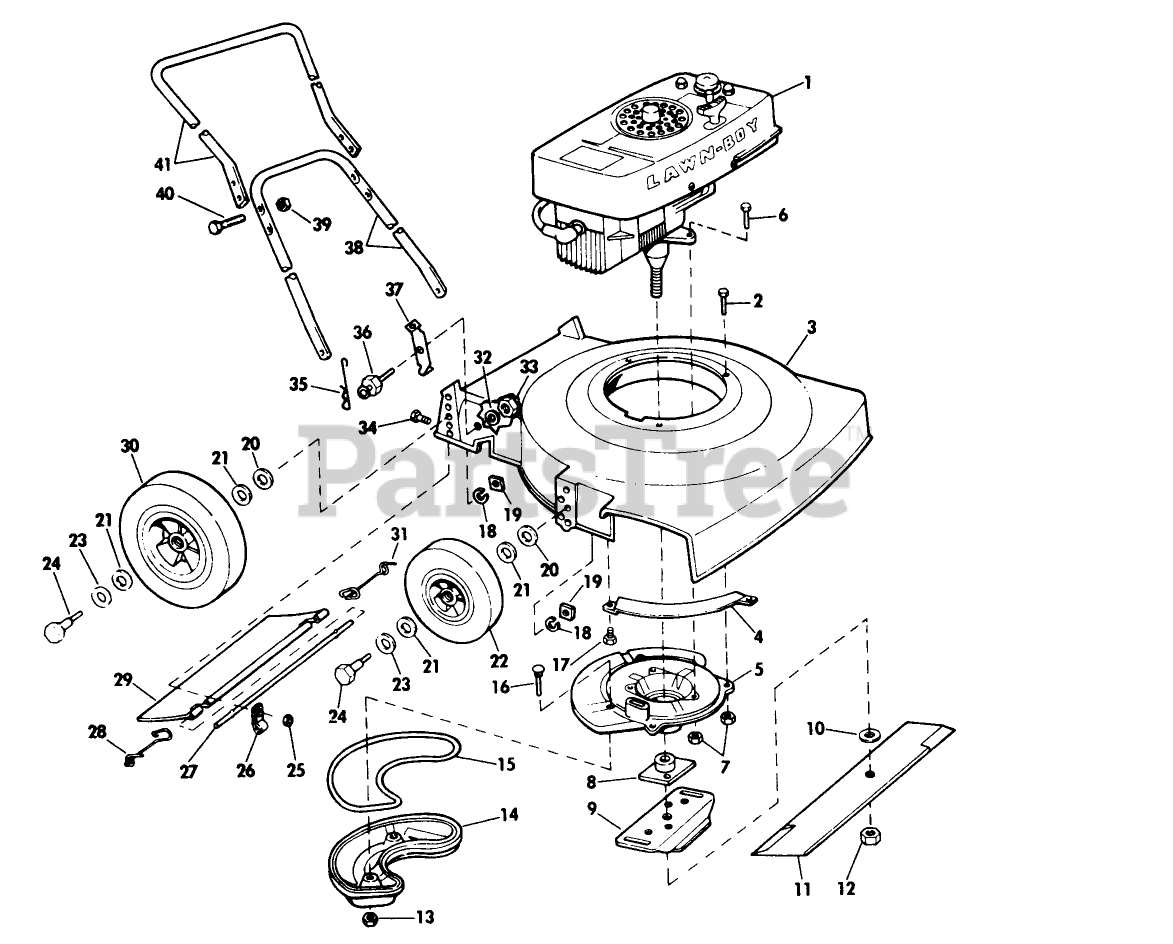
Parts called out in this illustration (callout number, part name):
2	SCREW
7	NUT
8	PLATE AND COLLAR ASM
10	WASHER
12	NUT-BLADE
13	LOCKNUT E
18	WASHER, LOCK
19	NUT
20	WASHER WROUGHT
21	WASHER
22	WHEEL & TIRE KIT
23	SPACER
24	BOLT
26	CLAMP ROD KMC
28	SPRING;TRAILING SHIELD RH
31	SPRIG T/SHLD ASOC
32	Lockwasher
40	SCREW
